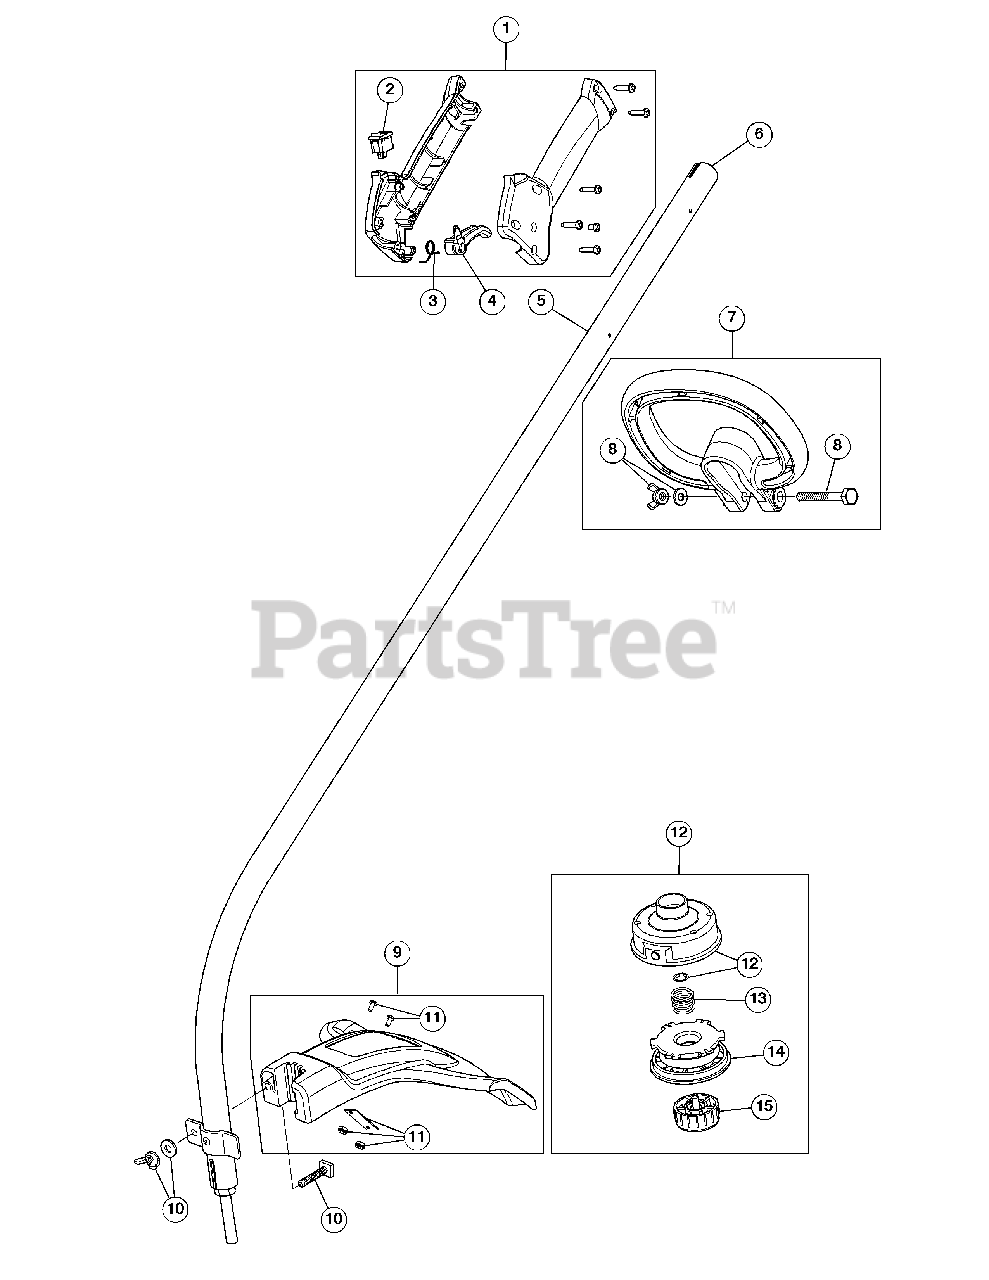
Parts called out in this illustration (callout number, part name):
1	Throttle Housing Assembly (Incl. 2 - 4)
2	Switch Assembly
3	Throttle Trigger Spring
4	Throttle Trigger
5	Drive Shaft Housing Assembly (Incl. 6)
6	Flexible Drive Shaft
7	D-Handle Assembly (Incl. 8)
8	D-Handle Hardware
9	Shield Assembly (Incl. 10 & 11)
10	Shield Mounting Hardware
11	Blade Assembly
12	Outer Spool Assembly (with Retainer)
14	Inner Reel
15	Bump Head Knob Assembly
